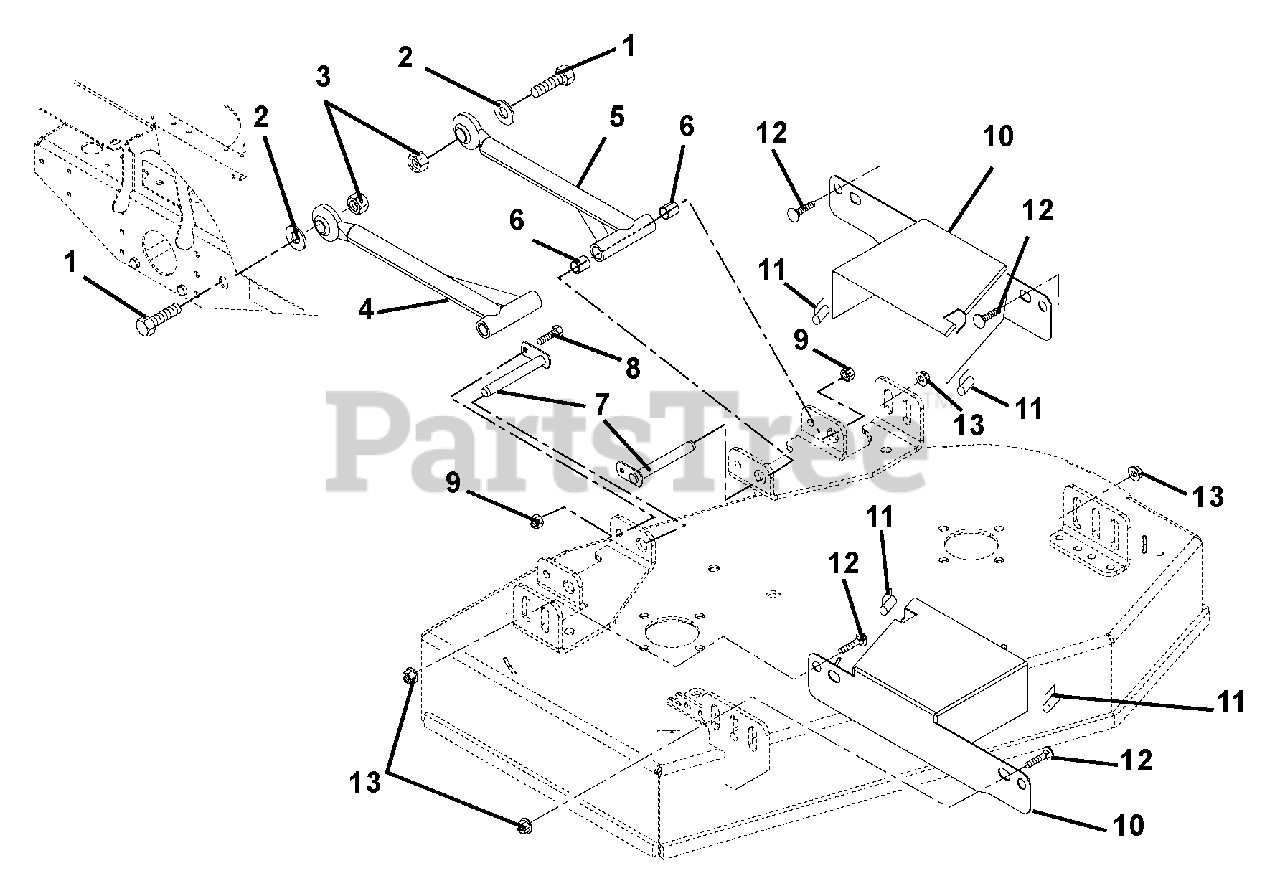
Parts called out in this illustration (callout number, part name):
1	BLT-HEX .875-9X3.00 GR5 YZ
2	BSHG-SLV .882X1.250X.531
3	NUT-LK-CTR .875-9 YWZC
4	ASSY, MOWER MOUNTING
5	MOWER MTG ARM - BLACK
6	BRG, .750 X .875 X 1.000
7	WELDMENT, MOWER MTG. PIN
8	BLT-HEX .38-16X.875 GR5 YWZC
9	@NUT-LK-NYL-FLG .38-16 YWZC
10	GUARD, 34" BELT
11	SEAL, TRIM-LOK BULK .06 BBL 1'
12	@BLT-RDHDSQNK .50-13X1.00 G5YZ
13	@NUT-LK-NYL-FLG .50-13 YWZC
